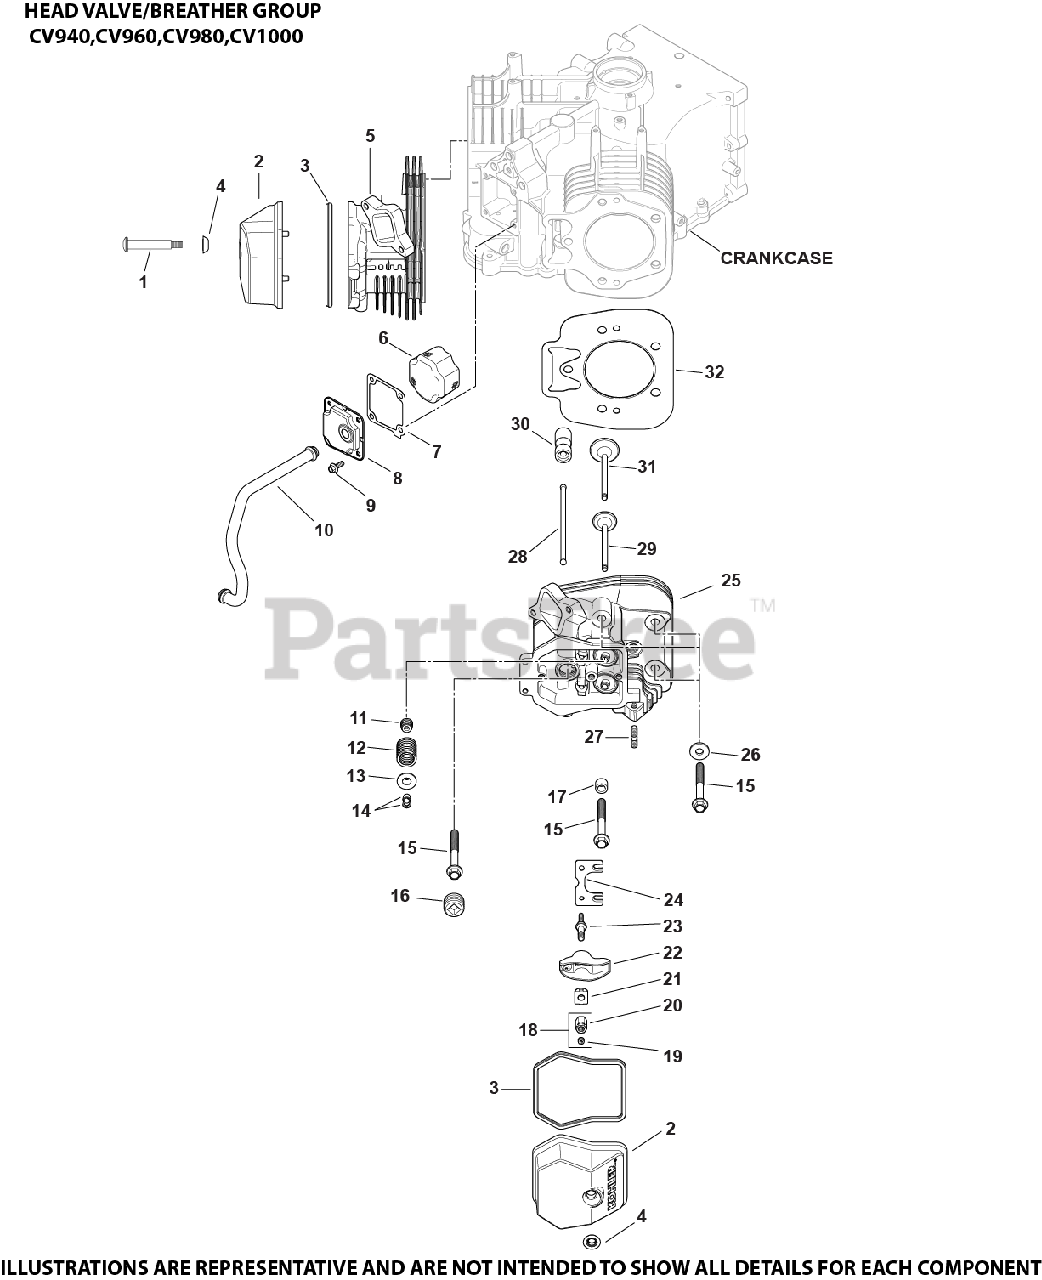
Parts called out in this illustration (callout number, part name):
1	SCREW, SHOULDER
2	KIT, COVER, VALVE (NO OIL FILL)
3	SEAL, VALVE COVER
4	GROMMET, VALVE COVER SCREW
5	KIT, CYLINDER HEAD #1 USE 62 318 12-S
6	FILTER, BREATHER USE 62 050 10-S
7	GASKET, BREATHER
8	KIT, BREATHER ASSEMBLY
9	SCREW, THREAD FORMING
10	HOSE, BREATHER (VERTICAL)
11	SEAL, VALVE STEM - (#2503214S)
12	SPRING, VALVE
13	CAP, VALVE SPRING
14	KIT, RETAINER
15	SCREW, FLG M10X1.5X90
16	PLUG, PIPE 3/4 NPTF SQ CTSK USE 25 139 89-S
18	HEX NUT ASSEMBLY
19	SCREW, SET
21	PIVOT, ROCKER ARM
22	ARM, ROCKER
23	STUD, ROCKER
24	PLATE, GUIDE - DISCONTINUED
25	KIT, CYLINDER HEAD #2 USE 62 318 13-S
26	WASHER, FLAT 13/32"
28	ROD, PUSH
29	VALVE, EXHAUST
30	LIFTER, VALVE HYDRAULIC - (#2535111S)
31	VALVE, INTAKE
32	KIT, CYLINDER HEAD GASKET
